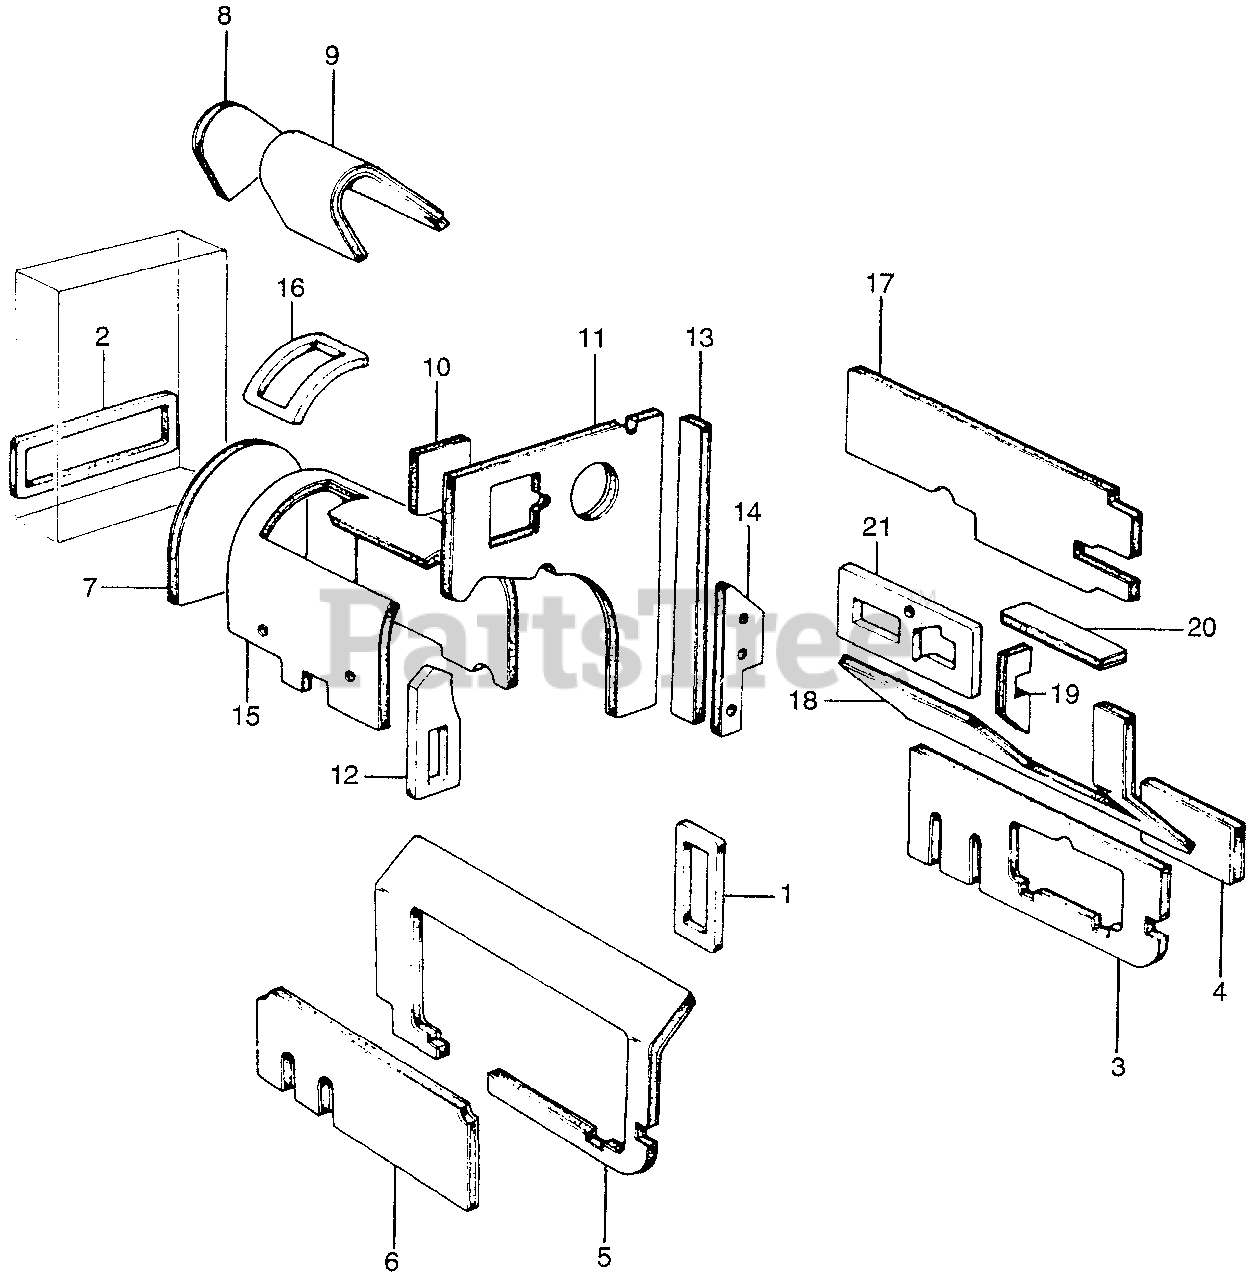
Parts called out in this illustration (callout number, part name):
1	SEAT, FAN COVER
2	SEAL, SHEET BOX
3	SHEET, R. SIDE COVER
4	SHEET, R. SIDE SUB-COVER
5	SHEET, L. SIDE COVER
6	SHEET, L. SUB-COVER
7	SHEET, ALTERNATOR END COVER
8	SHEET A, COVER
9	SHEET B, COVER
10	SHEET, POINT COVER
11	SHEET A, SEPARATOR
12	SHEET B, SEPARATOR
13	SHEET D, SEPARATE
14	SHEET, SEPARATOR
15	SHEET A, ALTERNATOR COVER
16	SHEET B, ALTERNATOR COVER
17	SHEET A, CARBURETOR SEPARATOR
18	SHEET B, CARBURETOR SEPARATOR
19	SHEET D, CARBURETOR SEPARATOR
20	SHEET F, CARBURETOR SEPARATOR
21	SHEET G, CARBURETOR SEPARATOR
